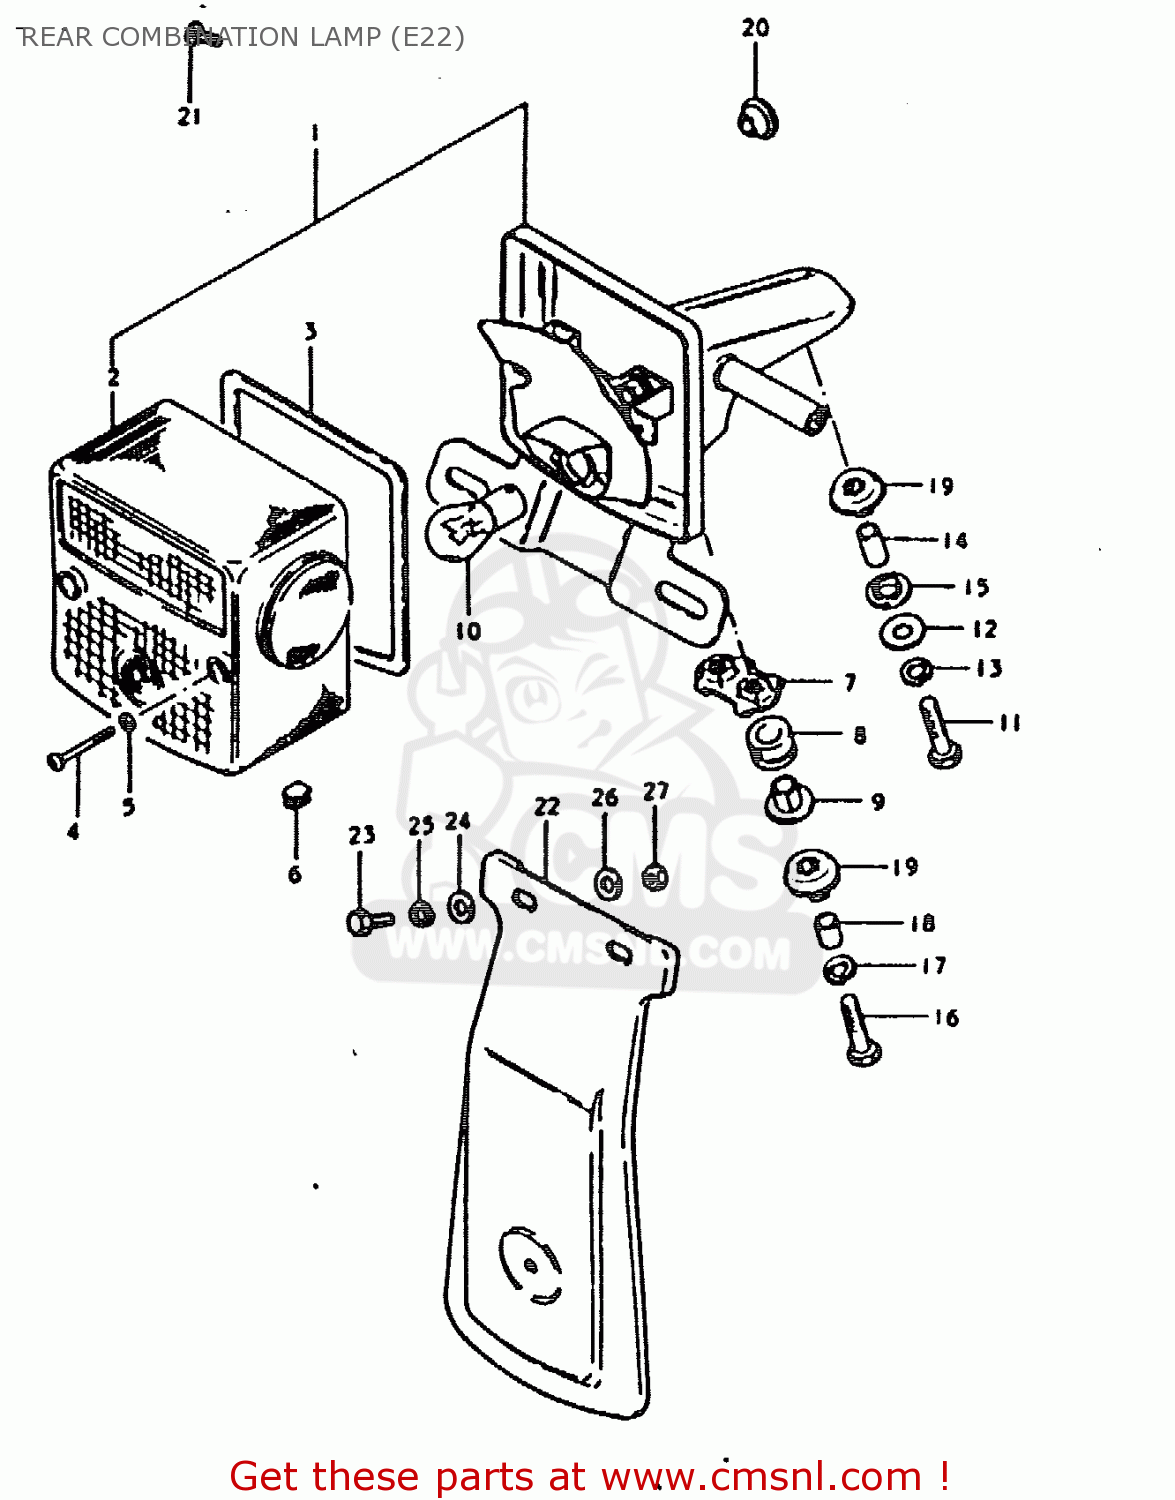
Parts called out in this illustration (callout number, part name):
1	LAMP ASSY, REAR COMBINATION
2	LENS
3	GASKET (NAS)
4	SCREW (4X55)
5	GASKET (NAS)
6	GROMMET,REAR COMBINATION LAMP
7	PLATE
8	CUSHION
9	SPACER
10	BULB (6V,21/5W)
11	BOLT
12	WASHER (6.5X20X1.2)
13	LOCK WASHER
14	SPACER
15	CUSHION
16	BOLT 6X40
17	LOCK WASHER
18	SPACER (6.8X10X11.5)
19	CUSHION
20	GROMMET
21	SCREW 5X6
22	MUD GUARD,REAR FENDER
23	BOLT, UPPER
24	WASHER
25	LOCK WASHER
26	WASHER
27	NUT
